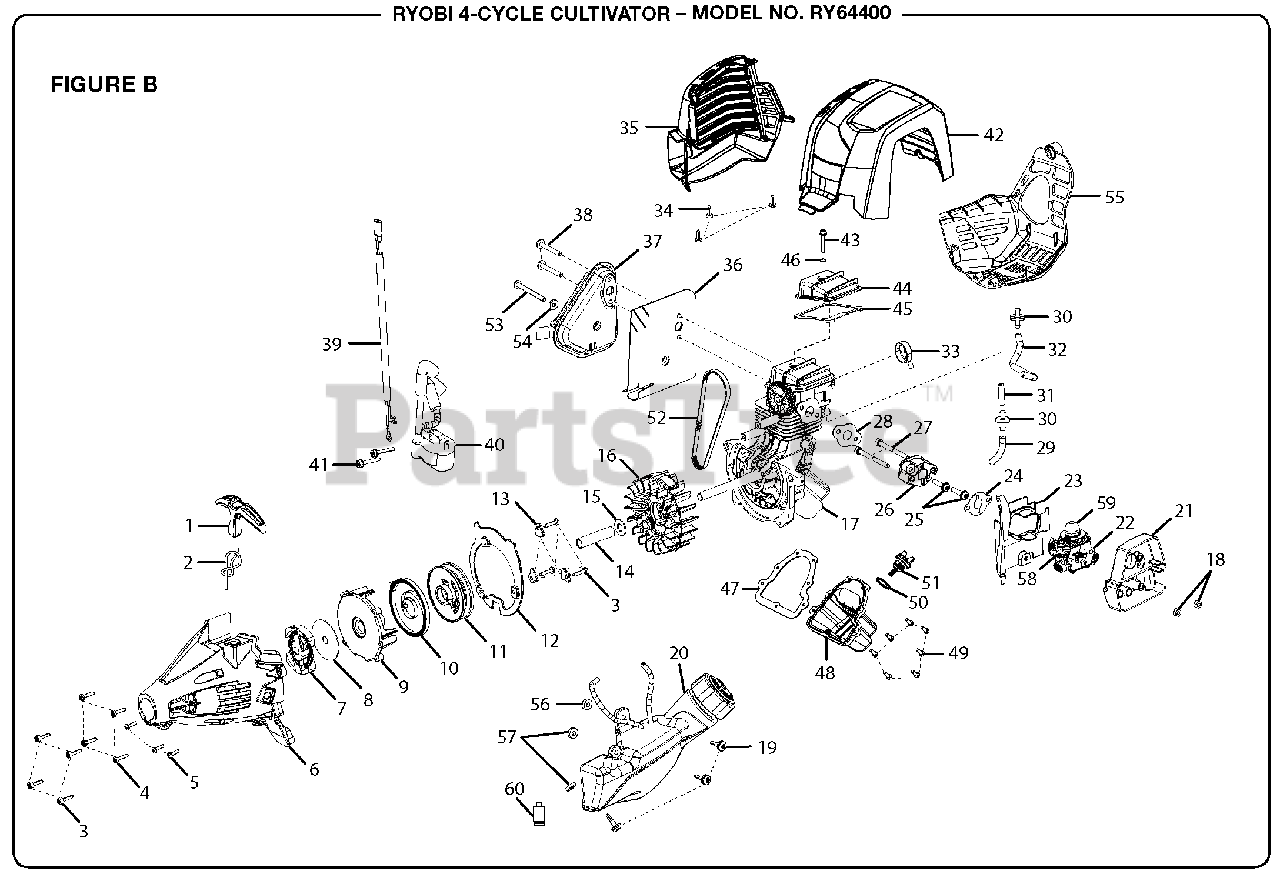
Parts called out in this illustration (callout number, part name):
1	Starter Grip
2	Starter Rope
3	Screw (M4 x 18 mm)
4	Screw (M4 x 16 mm)
5	Screw (#6 x 1/2 in. T.F.)
6	Starter Housing Assembly
7	Clutch Assembly
9	Starter Baffle
10	Spring & Container
13	Pulley Retainer
14	Spacer Tube
15	Washer
16	Flywheel Assembly
17	Short Block Assembly (Incl. Key Nos. 43-52)
19	Screw (M4)
20	Fuel Tank & Cap Assembly
21	Air Box Base
22	Carburetor Assembly
23	Air Baffle
24	Carburetor Gasket
25	Screw (M5 x 23 mm)
27	Bolt
28	Heat Dam Gasket
29	Breather Hose
30	Check Valve
31	Breather Hose
32	Breather Hose
33	Breather Fitting
34	Screw (M4 x 12 mm)
35	Muffler Housing
36	Muffler Gasket
37	Muffler Assembly
38	Muffler Bolt (M5 x 42 mm)
39	Electrical Lead Wire Assembly
40	Ignition Module
41	Screw (M4 x 19 mm)
42	Top Housing
43	Screw (M4 x 27 mm total, 14 mm threaded)
44	Cam Cover
49	Screw (M4 x 12 mm)
51	Oil Cap/Dipstick
52	Timing Belt
53	Muffler Bolt (M5 x 50 mm)
55	CE Cover (Bottom Cover)
56	Washer (Plastic)
58	Choke Lever
59	Primer Bulb
60	Fuel Filter
